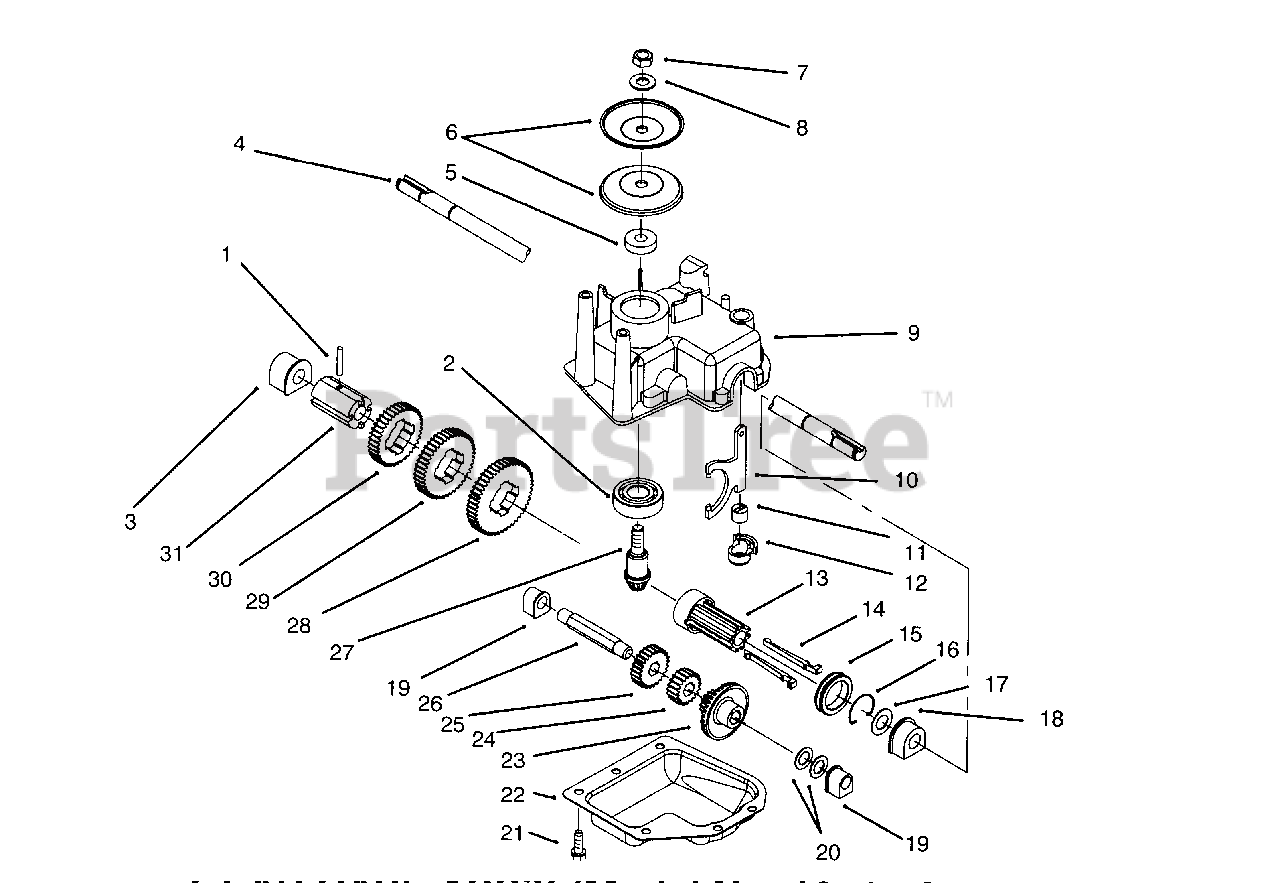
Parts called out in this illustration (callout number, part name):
1	Pin-Groove
2	Bearing-Ball
3	Bushing-Output
4	Shaft- Output
6	Pulley-Half
9	Gearcase-Upper
10	Yoke-Shift
11	Bushing-Yoke
12	Retainer-Shift Fork
13	Sleeve-Shift Key
14	Key-Shift
15	Collar-Shift
16	Clip-Spring
18	Bushing-Output
19	Bushing-Inter. Shaft
20	Washer-Thrust
22	Gear Case Cover
23	Pinion-15 Tooth
24	Pinion-20 Tooth
25	Pinion-25 Tooth
26	Shaft-Intermediate
27	Pinion-Bevel
28	Gear-49 Tooth
29	Gear-44 Tooth
30	Gear-39 Tooth
31	Sleeve-Gear
